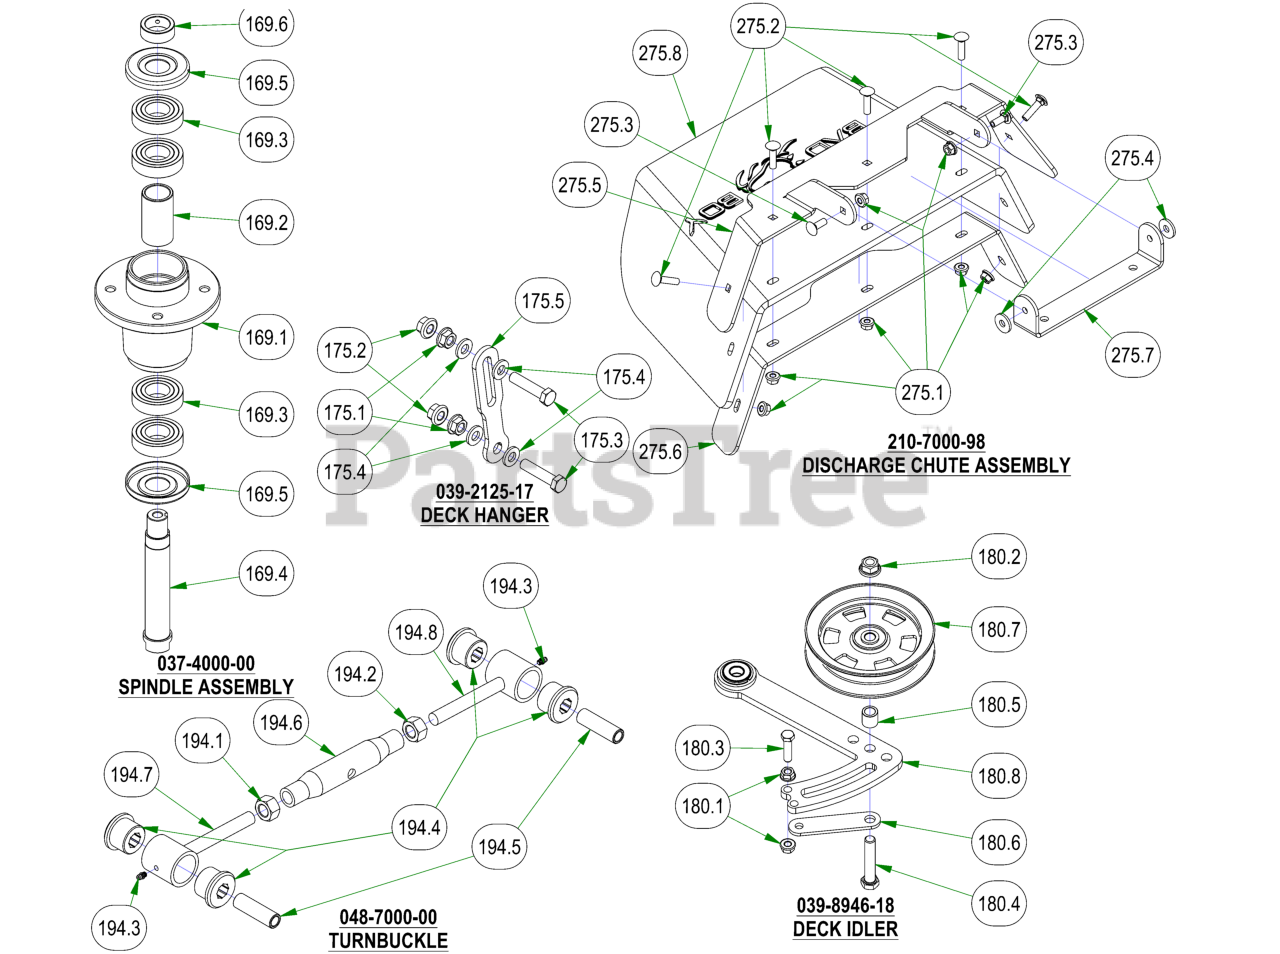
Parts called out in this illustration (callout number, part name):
169	OUTLAW SPINDLE ASSEMBLY
169.1	4000 Series Spindle Housing
169.2	4000 Series Spindle Spacer
169.3	Bearing - 6206
169.4	Spindle Shaft
169.5	Spindle Dust Cap
169.6	Locking Collar w/ 1/4"-20 Set Screw
175	Deck Hanger Assembly
175.1	1/2-13 HEX SERRATED FLANGE NUT HARD/ZINC
175.2	1/2-13 NYLON INSERT FLANGE LOCKNUT ZINC
175.3	1/2-13 X 2-1/4 HEX CAP SCREW (GR.5) ZINC
175.4	.505 ID X 1.000 OD X .125 THICK FLAT WASHER NYLON
175.5	Deck Hangar
180	2019 Rebel Rogue Deck Idler
180.1	3/8-16 HEX SERRATED FLANGE NUT HARD/ZINC
180.2	1/2-13 NYLON INSERT FLANGE LOCKNUT ZINC
180.3	3/8-16 X 1-1/2 HEX CAP SCREW (GR.5) ZINC
180.4	1/2-13 X 2-3/4 HEX CAP SCREW (GR.5) ZINC
180.5	.51 ID X .75 OD X .75 LGTH SOLID SPACER ZINC
180.6	Belt Tensioner Retainer Plate
180.7	5" Idler Pully
180.8	2019 Deck Tensioner
194	Turnbuckle
194.1	11/16-12 Hex Nut-2015 Toplink
194.2	11/16-12 Lefthand Hex Nut-Topl
194.3	1/4" Press in Grease Fitting
194.4	Polyeurethane Bushing
194.6	2015 Outlaw Toplink Body
194.7	2015 Outlaw Toplink RH End
194.8	2015 Outlaw Toplink LH End
275	2019 Outlaw Gen2 Chute Assembly
275.1	5/16-18 NYLON INSERT FLANGE LOCKNUT ZINC
275.2	5/16-18 X 1-1/4 CARRIAGE BOLT ZINC
275.3	5/16-18 X 7/8 CARRIAGE BOLT ZINC
275.4	.360 ID X .983 OD X .120 THICK FLAT WASHER NYLON
275.5	2019 Upper Chute Bracket
275.6	2019 Lower Chute Bracket
275.7	2019 Chute Hanger
275.8	2019 Belted Chute with Logo
